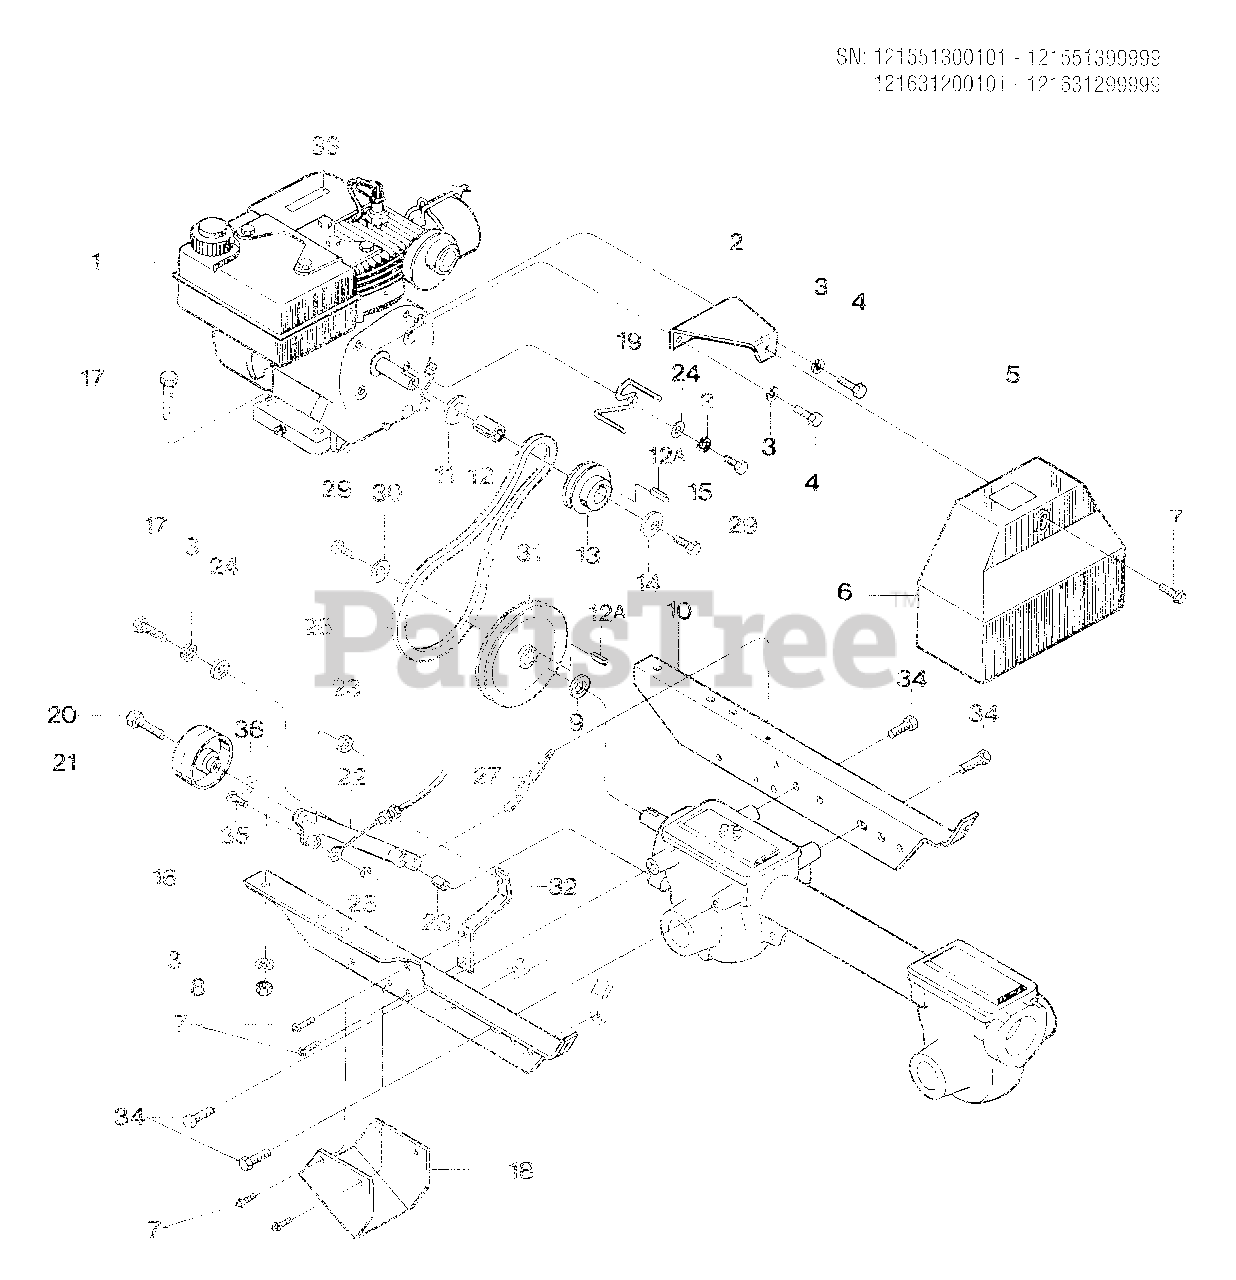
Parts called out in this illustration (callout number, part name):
1	Engine- Tecumseh, recoil start
2	Bracket, Belt Cover
3	Lockwasher-5/16
4	Bolt-Hex Hd., 5/16-24 x 1/2
5	Decal-Warning, Hot Surfaces
6	Belt Cover
7	Bolt-Flanged Hd., Self-Tapping, 1/4-20 x 1/2
8	Nut-Hex Hd., 5/16-18
9	Support Washer
10	Bracket, Engine, Right
11	Shim
12	Spacer
12A	Key-3/16 x 1
13	Pulley, Engine Driven
14	Washer, Belleville
15	Bolt-Hex Hd., 3/8-24 x 1
16	Bracket, Engine, Left
17	Bolt-Hex Hd., 5/16-18 x 1-1/2
18	Belt Pulley Guard
19	Belt Guide
20	Bolt-Hex Hd., 3/8-16 x 1-1/2
21	Idler Pulley
22	Idler Lever
23	Locknut - 3/8-16
24	Washer, Flat
25	Klip Ring
26	V-Belt
27	Spring, Return
28	Bushing-Idler Lever
29	Bolt-Hex Hd., 5/16-24 x 3/4, Grade 5
30	Washer, Belleville, Transmission Pulley
31	Pulley-Transmission
32	Bracket-Cable Mount
33	Decal-Stabilization
34	Bolt-5/16-18 x 5/8, Engine Bracket to Transmission
35	Clevis Pin-Control Cable
36	Washer-flat, 3/8
